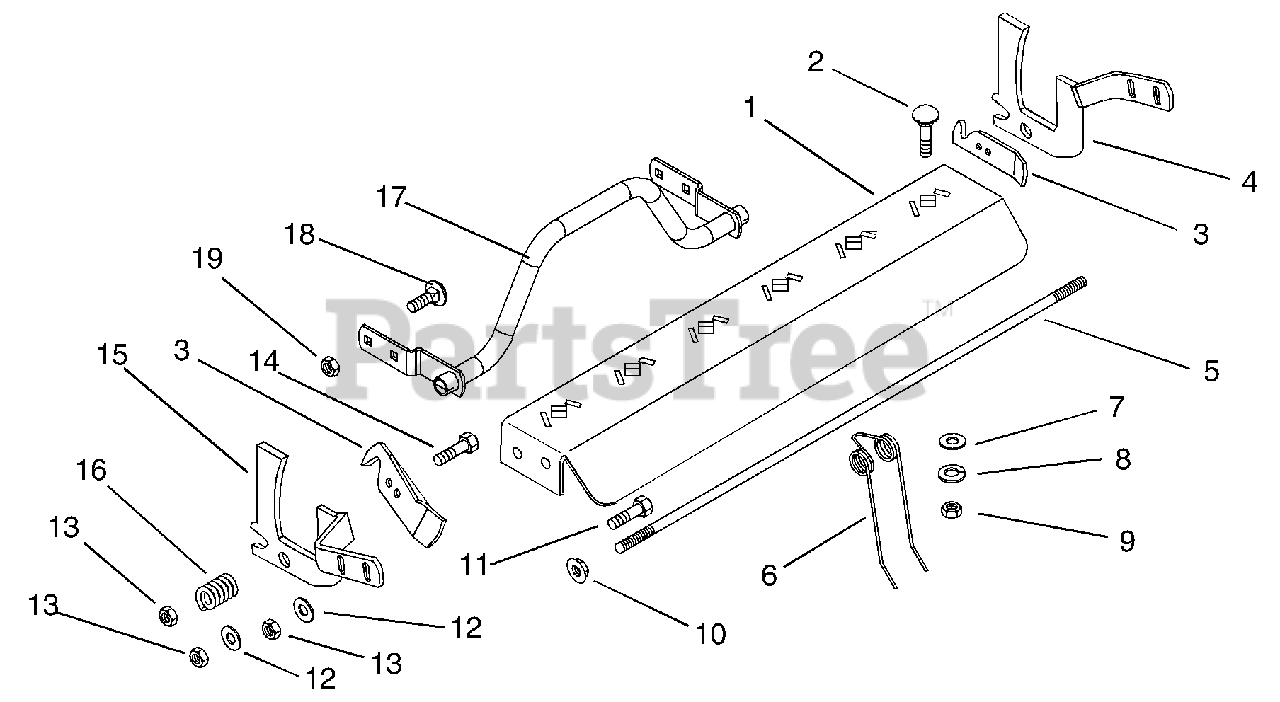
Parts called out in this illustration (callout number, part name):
1	Tine Plate
2	Bolt-Round Head Square Neck .31-18 x .75 Grade 2
3	Axle Lock
4	Cam Bracket-Left Hand
5	Rod, Retention
7	Washer-Flat-Steel .328 x 1.0 x .094
8	Washer-Locking .312 x .097
9	Nut-Hex .31-18
10	Nut-Locking-Flange .250-20
11	Bolt-Hex .25-20 x .75 Grade 5
12	Washer-Flat-Steel .281 x .62 x .065
13	Nut-Locking-Center .25-20
14	Bolt-Hex .25-20 x 1.25 Grade 5
15	Cam Bracket-Right Hand
16	Spring-Compression .058 x .68 x .75
17	Dethatcher Retainer Weldment
18	Bolt-Round Head Square Neck .31-18 x .62
19	Nut-Locking-Center .31-18
